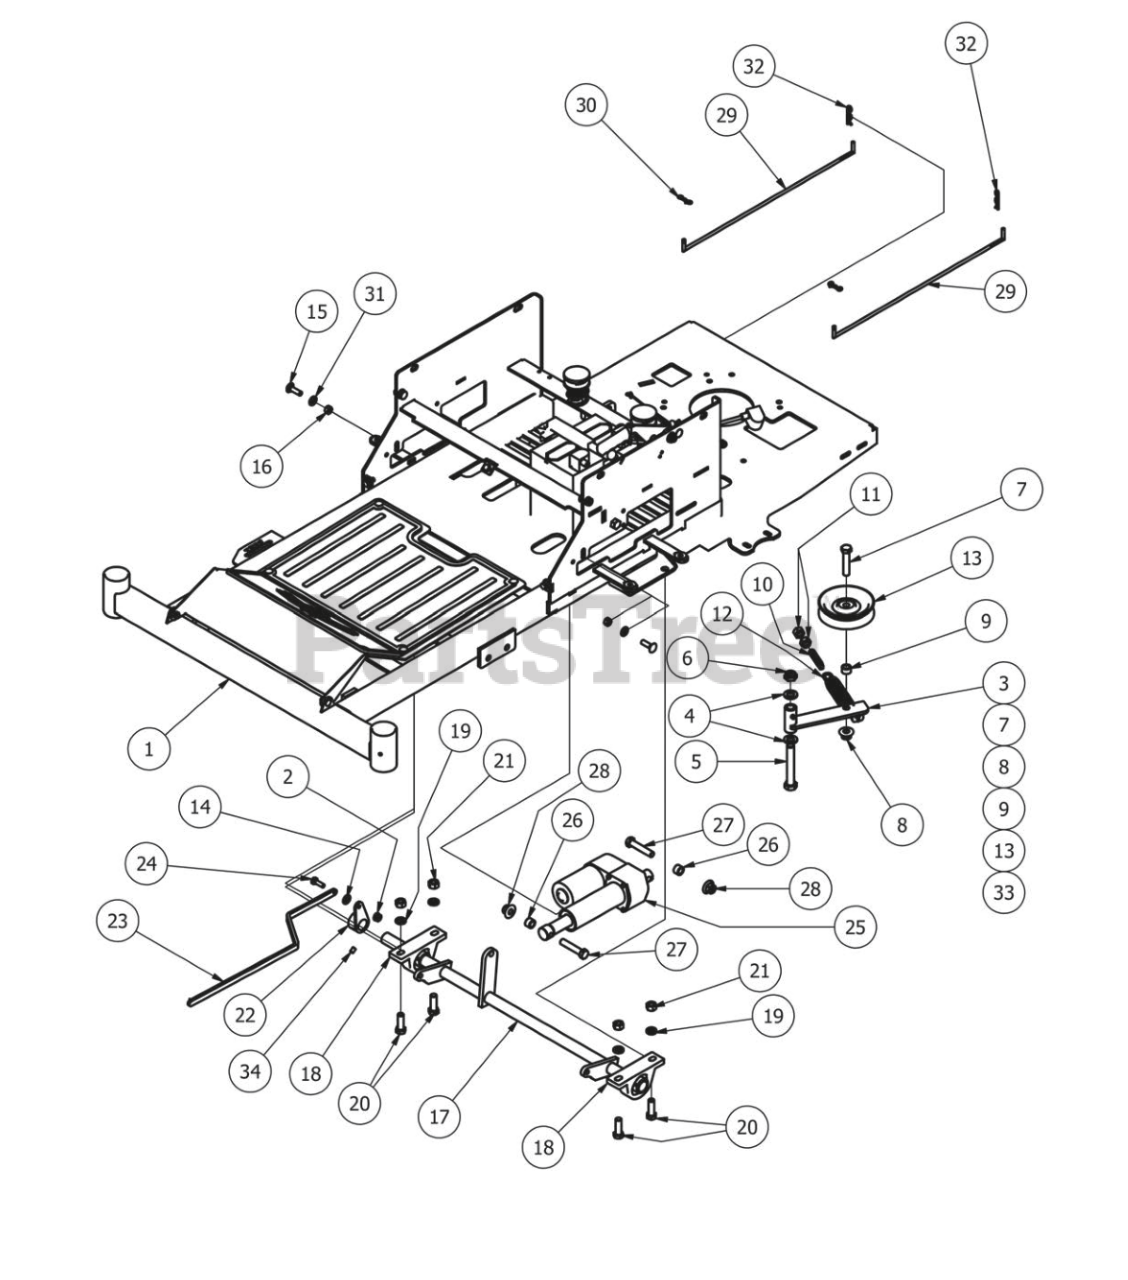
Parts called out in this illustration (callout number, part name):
1	ZT/CZT Frame 2013 Models
2	5/16-18 Nylon Flange Nut
3	Pump Idler Bracket
4	.635 ID Plastic Washer
5	5/8" x 4" Hex Bolt
6	5/8" Nylock (1/2 Jam)
7	1/2" x 2 1/2" Hex Bolt
8	1/2-13 Nylon Flange Nut-Orange
9	1/2 x 1/2 Spacer
10	All Thread-pump Idler Tensioner
11	1/2" Hex Nut
12	2009 Deck/Pump Idler Spring
13	4 3/4" Idler Pulley
14	.360 ID Plastic Washer
15	3/8" x 1 1/4" Carriage Bolt
16	3/8" Hex Nut
17	Actuator Bar-Transaxle
18	pillow block 2bolt sealmaster
19	1/2" Lock Washer
20	1/2" x 1 1/2" Hex Bolt
21	1/2" Hex Nut
22	Height Indicator Lever
23	Height Indicator Bar
24	5/16" x 1" Bolt
26	1/2 x 1/2 Spacer
27	1/2" x 2 1/2" Hex Bolt
28	1/2-13 Nylon Flange Nut-Orange
29	ZT Neutral level rod 2011
31	3/8" Flat Washer
32	Neutral Rod Clip
33	Pump Idler Assembly (Components 3,7,8,9,13)
34	5/16 Set Screw
